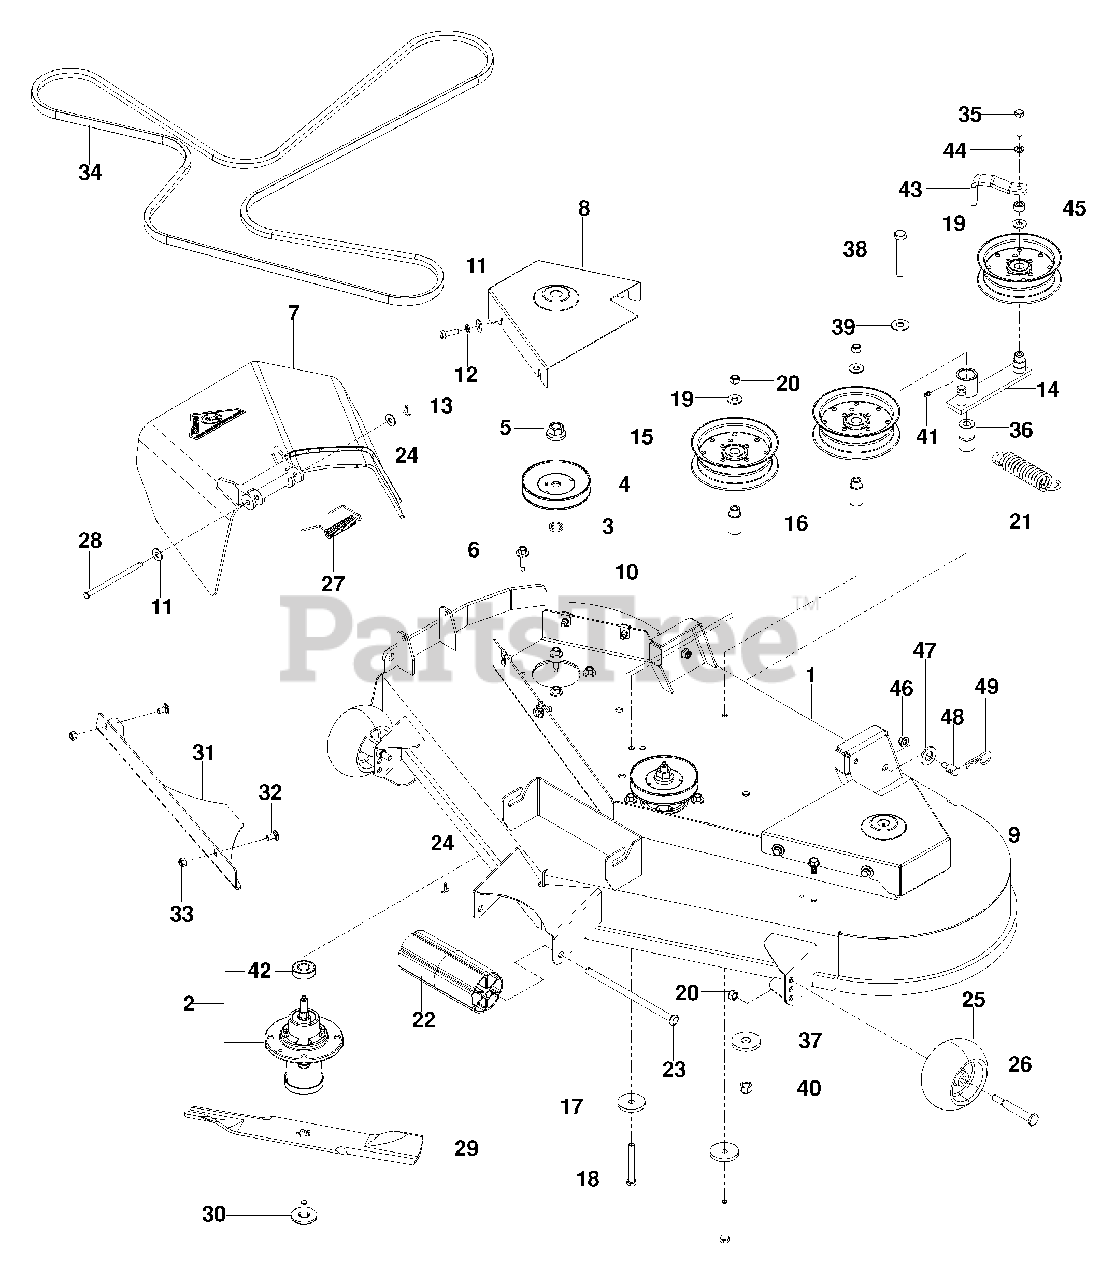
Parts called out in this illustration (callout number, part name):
1	DECK, w/DECALS
2	HOUSING ASSY
3	WASHER, SPACER
4	PULLEY, MANDREL
5	NUT 9/16 TOP CNTRLK
6	SCREW 5/16 -18 x WSH HD
7	CHUTE, DISCHARGE
8	BELT SHIELD, RT
9	BELT SHIELD, LT
10	RETAINER, U TYPE
11	WASHER 5/16 STD FLAT
12	WASHER 5/16 SLW
13	HCS 5/16-18 x 3/4
14	ARM, IDLER
15	PULLEY, IDLER
16	BUSHING, IDLER
17	WASHER, HEAVY
18	HCS 3/8-16 x 3
19	WASHER 3/8 FLAT STD
20	NUT 3/8-16 HEX NYLOC
22	ROLLER, NOSE
23	ROD, ROLLER NOSE
24	PIN, COTTER 1/8 x 3/4
25	WHEEL, GAUGE
26	BOLT 1/2-16 x 25/8 SHOULDER
27	SPRING, TORSION
28	PIN, CLEVIS 5/16
30	BOLT 7/16 BLADE
31	PLATE, CONFINEMENT
32	RHSNB 5/16-18 x 5/8
33	NUT 5/16-18 HEX NYLOC
34	BELT, DECK
35	HCS 3/8-16 x 1 3/4
36	BUSHING, PIVOT
37	WASHER, SUPPORT
38	HCS 1/2-13 x 3 1/4
39	WASHER 1/2 STD FLAT
40	NUT 1/2 HEX NYLOC
41	ZERK
42	BEARING, BALL
43	GUIDE, BELT
44	WASHER 5/16 SAE FLAT
46	NUT 5/16-18 FLANGE NYLOC
47	WASHER 5/8 FLAT SAE
48	STUD w/ ANTI-ROTATE
